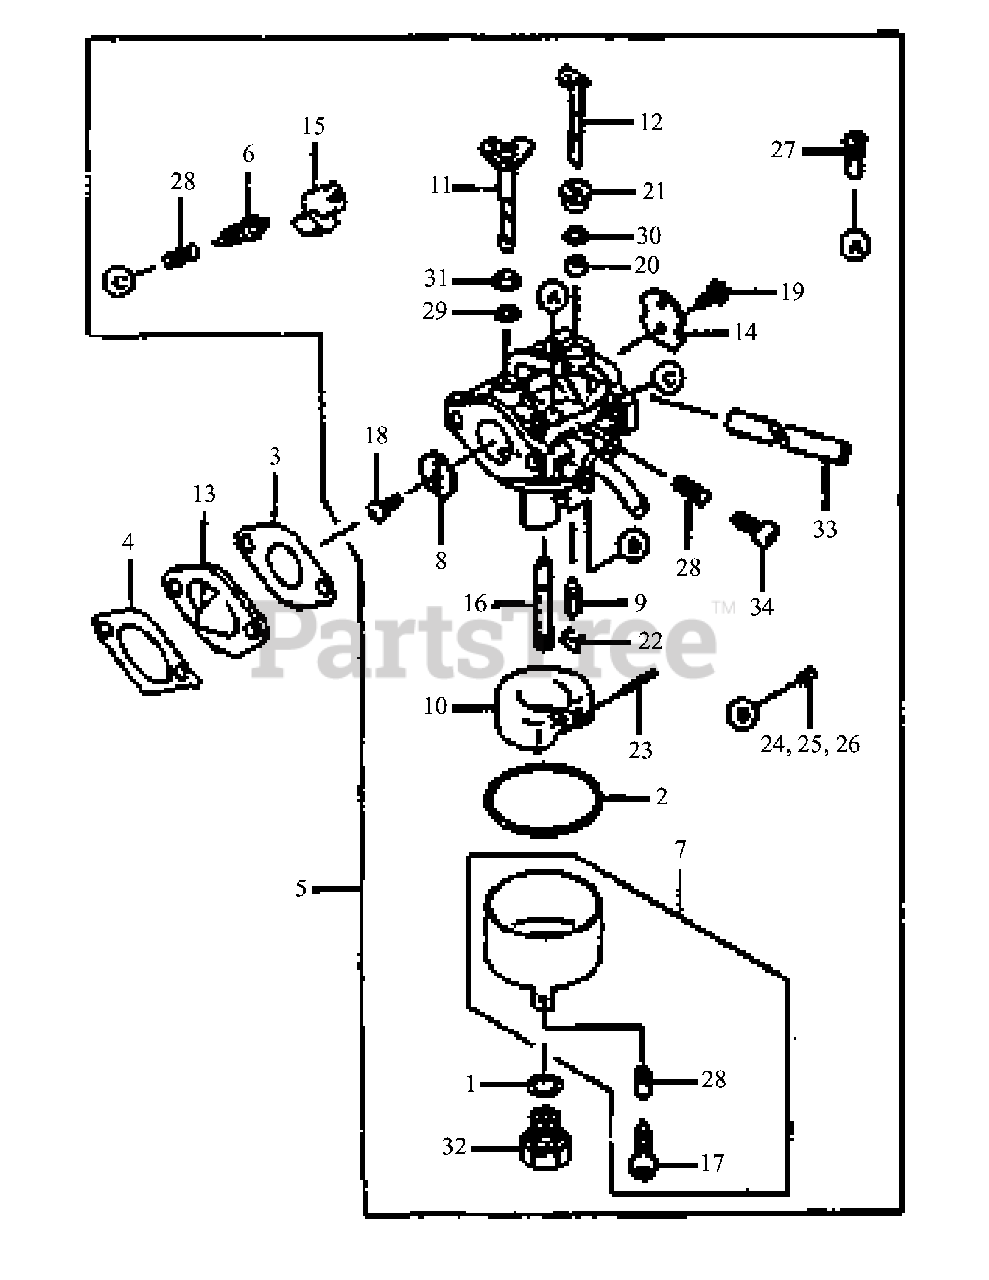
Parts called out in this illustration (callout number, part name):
1	Gasket
3	Gasket, Carburetor
4	Gasket, Insulator
6	Screw, Pilot Air
7	Chamber, Float
8	Valve, Throttle #130
11	Shaft, Throttle
19	Screw
24	Jet, Main #62.5
25	Jet, Main #60
26	Jet, Main #58.5
27	Jet, Pilot #37.5
32	Bolt
